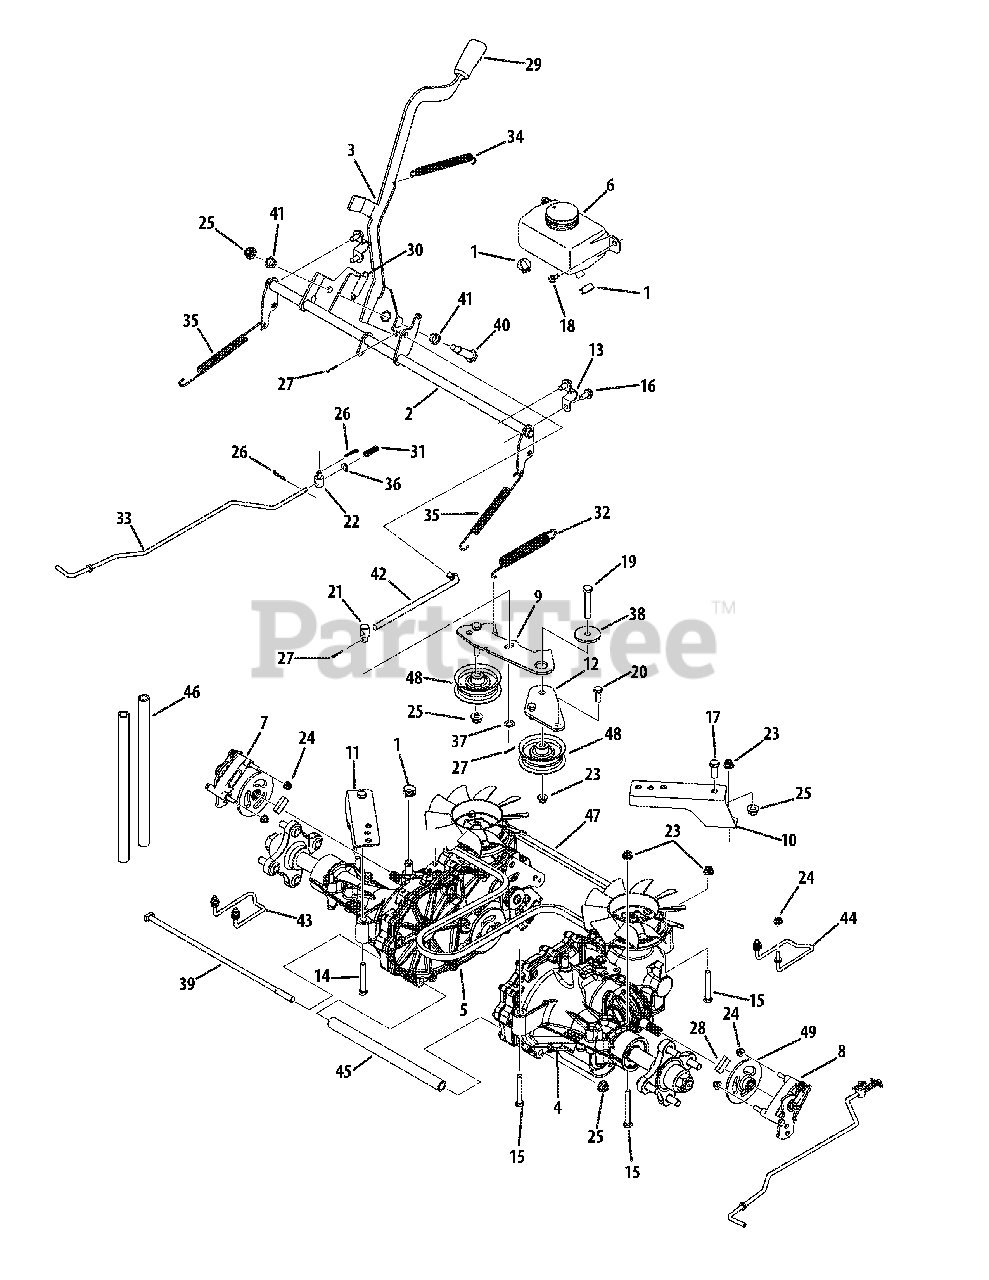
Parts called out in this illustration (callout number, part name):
1	Hose Clamp, 1/2inch
2	Brake Shaft Assembly
3	Brake Handle Assembly
4	RH Transmission Assembly
5	LH Transmission Assembly
6	Expansion Tank Assembly
7	LH Brake Assembly
8	RH Brake Assembly
9	Idler Bracket
10	RH Mount Bracket
11	LH Mount Bracket
12	Idler Mount Plate
13	Shaft Mount Bracket
14	Hex Screw, 5.16-18 x 2.75
15	Hex Screw, 5.16-18 x 2.25
16	Hex Washer Screw, 5.16-18 x .750
17	Hex Screw, 3.8-16 x 1.00
18	Hex Washer Screw, 1.4-20 x .500
19	Hex Screw, 3.8-16 x 2.25
20	Hex Screw, 5.16-18 x .875
21	Ferrule, 3.8-24 x .375
22	Ferrule, .325 x .312
23	Flange Lock Nut, 5.16-18
24	Flange Lock Nut, 1.4-20
25	Flange Lock Nut, 3.8-16
26	Cotter Pin, .072 x 1.13
27	Cotter Pin, 3.32 x .750
28	Brake Pad
29	Selector Handle
30	Extension Spring, .48 x 2.03
31	Compression Spring, .405 x 1.17
32	Extension Spring, .75 x 6.02
33	Transmission Bypass Lever Wire
34	Extension Spring, .50 x .6.37
35	Extension Spring, .500 x 7.0
36	Spring Washer, .265 x .562 x .025
37	Thrust Washer, .375 x .70 x .030
38	Shoulder Spacer, .884 x .190
39	Rod, .328 x 14.00
40	Shoulder Screw, .498 x 1.635
41	Flange Bearing, .500 x .34
42	Disenage Brake Rod
43	LH Rod Keeper
44	RH Rod Keeper
45	Transmission Spacer, 10.5
46	Fuel Hose, 1.2 x 12.00
48	Flat Idler Pulley, 2.75
49	Brake Disc
